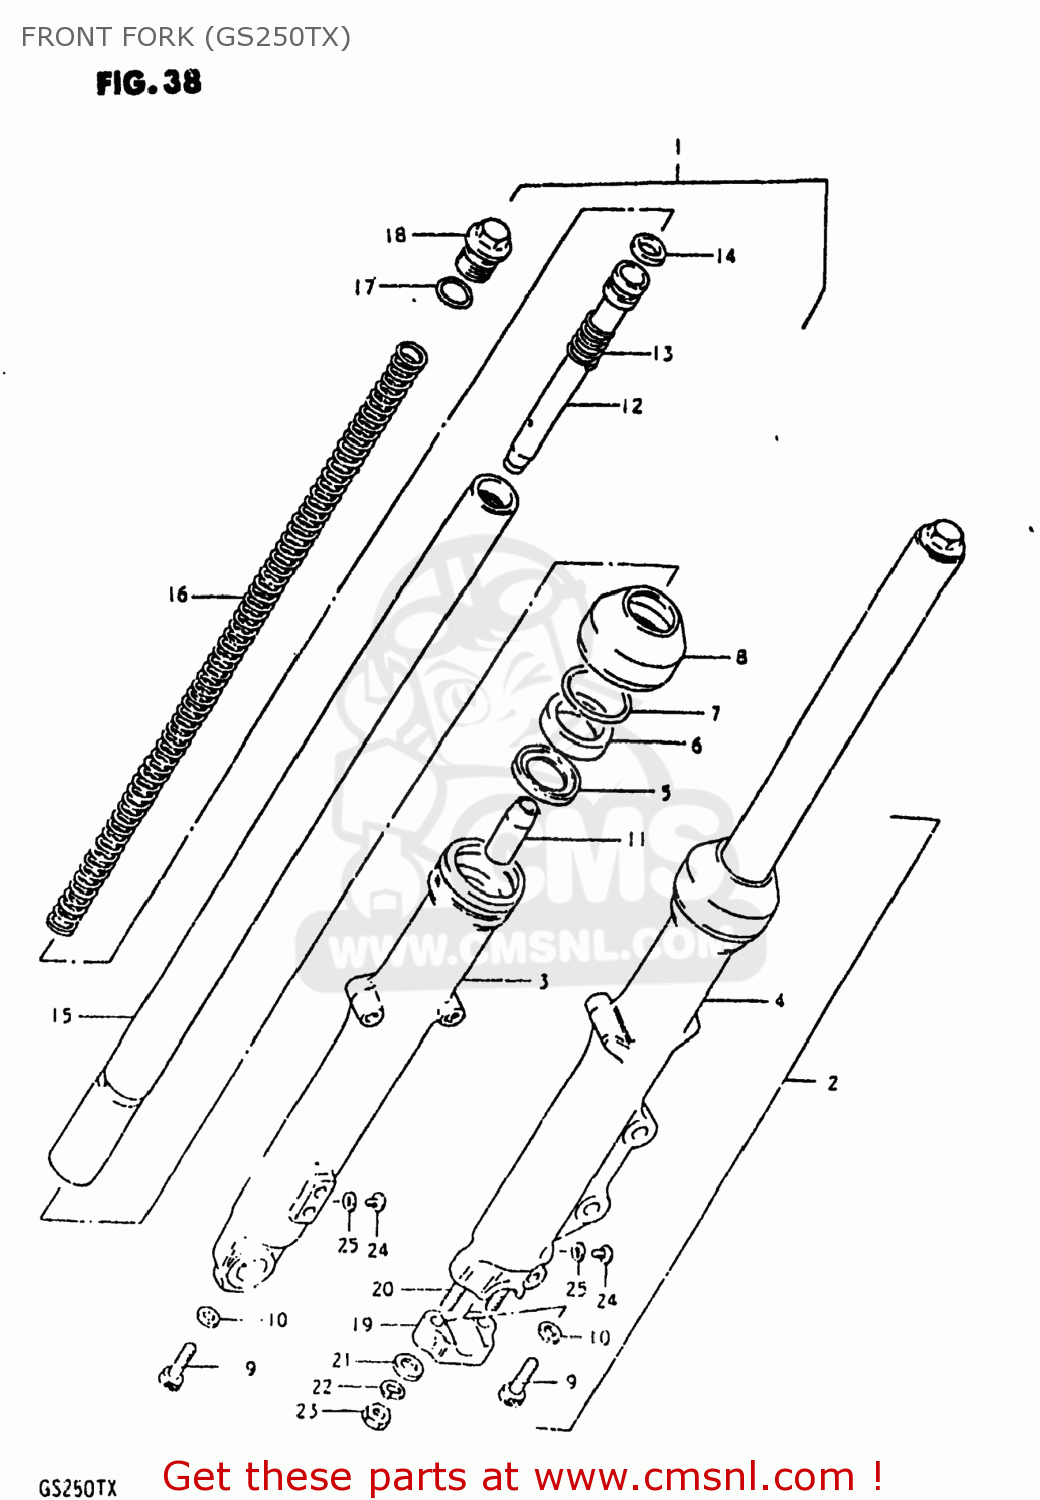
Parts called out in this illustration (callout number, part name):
1	DAMPER ASSEMBLY,FRONT FORK,RIGHT
2	DAMPER ASSEMBLY,FRONT FORK,LEFT
3	TUBE,FORK,OUTER,RIGHT
4	TUBE,FORK,LEFT,OUTER
5	SPACER,OIL SEAL
6	OIL SEAL,FRONT FORK
7	CIRCLIP,FORK OIL SEAL
8	BOOT
9	BOLT(8X27)
10	GASKET (NAS)
11	PIECE,OIL LOCK
12	CYLINDER,FRONT FORK
13	SPRING,REBOUND
14	RING,PISTON
15	TUBE,INNER
16	SPRING
17	O RING
18	BOLT
19	HOLDER,AXLE
20	STUD 8X25
21	WASHER
22	LOCK WASHER
23	NUT (8MM)
24	SCREW 4X6
25	GASKET (NAS)
